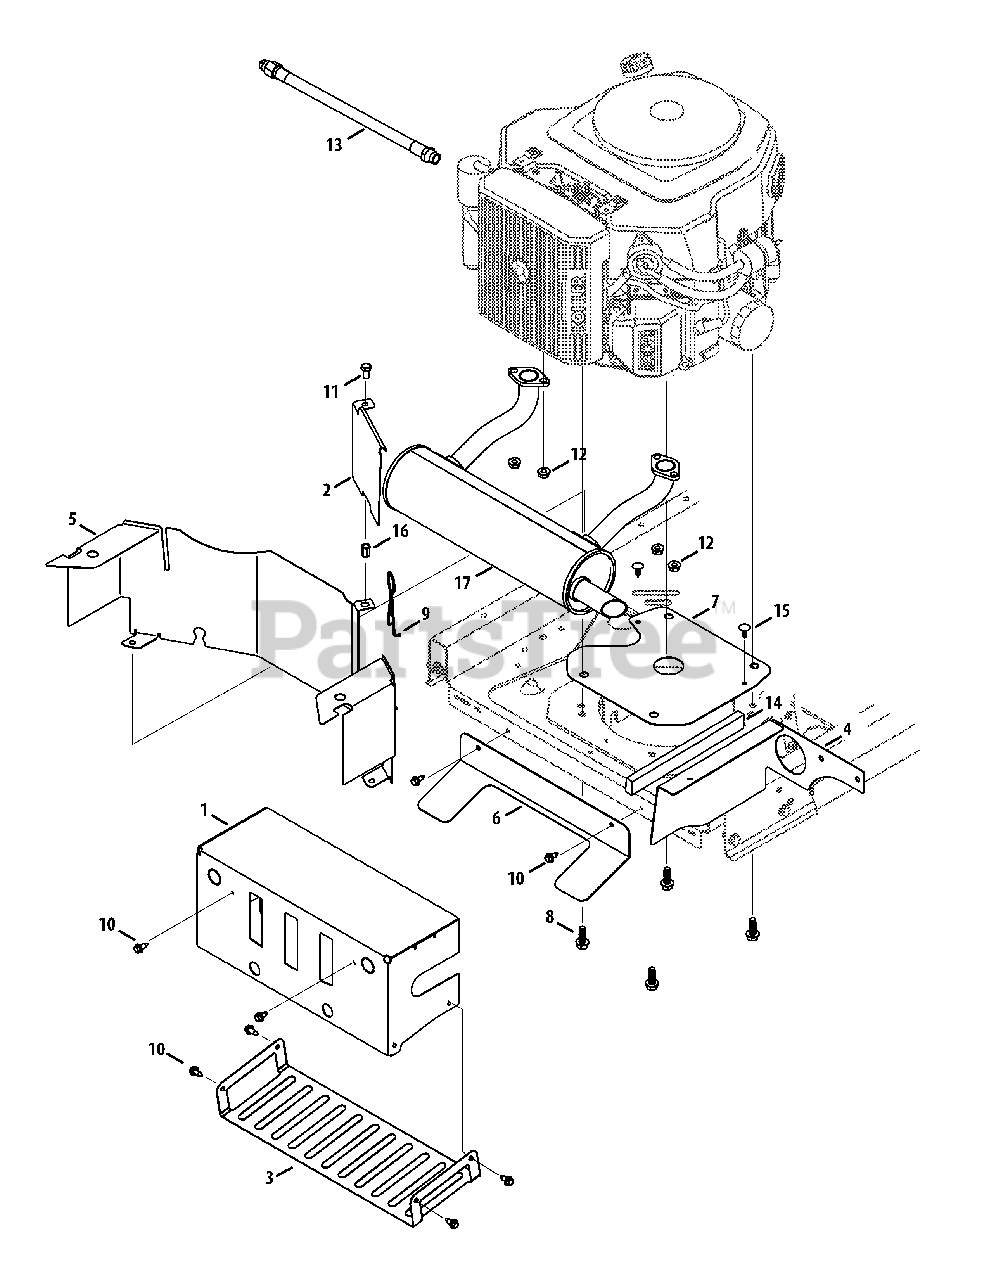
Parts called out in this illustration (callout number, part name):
1	Muffler Shield Bracket
2	Engine Shield Bracket
3	Lower Muffler Shield Bracket
4	Pod Shield Bracket, RH
5	Engine Shield Bracket
6	Muffler Shield Bracket
7	Engine Shield Plate
8	Screw, 3/8-16 x 1.00
9	Tank Support Rod
10	Hex Washer Screw, 1/4-20 x .625
11	Hex Cap Screw, 5/16-18 x .625
12	Nut, M8-1.25, Hex Flange
13	Oil Drain Hose
14	Foam Tape, 1.00 x .500 x 9.375
15	Ratchet Clip, .250
16	Nut, 5/16-18
17	Twin Muffler
